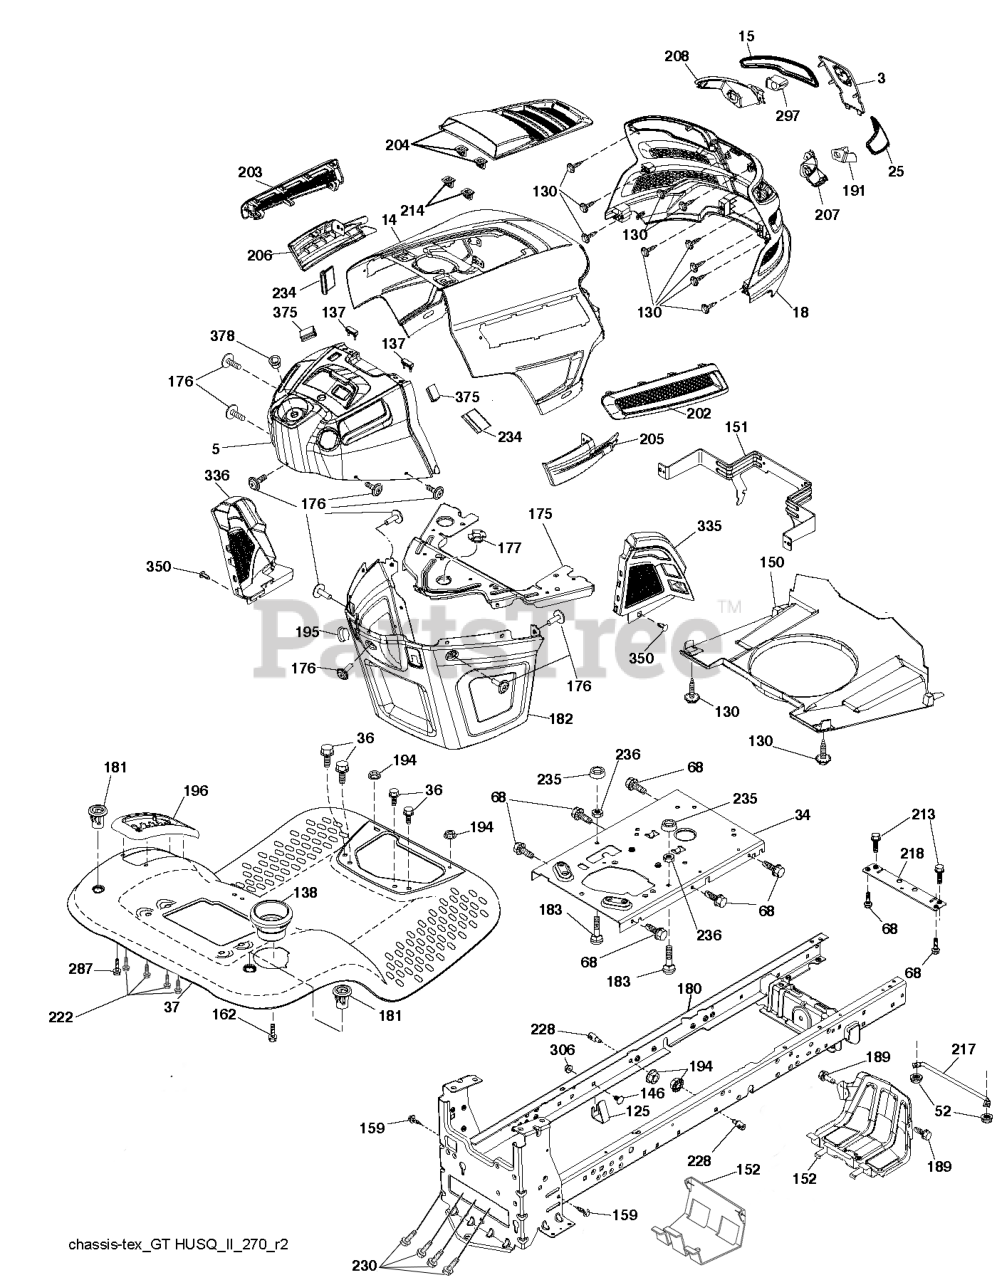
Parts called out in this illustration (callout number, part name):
3	APPLIQUE.SUBASM.GT.HUSQ.II
5	DASHBOARD.UPPER.ASM.GT2.X498
14	HOOD.ASM.HUSQVARNA.GT.TEX.ORAN
15	LENS.HEADLIGHT.LH.GTII.2011
15	LENS.LH.TEX.GT.HUSQ.CL
18	GRILLE SUBASM.GT.II.LOW.HDLGHT
25	LENS.HEADLIGHT.RH.GTII.2011
34	PLATE.ENGINE.WELDED.CHASSIS
36	SCREW 5/16"
37	FENDER.TLT.FS.W/CUPHLD.ORANGE
52	LOCKNUT
125	CLIP.FUEL.LINE
137	BUMPER DASH
138	HOLDER.CUP.LT.GREY
146	BOLT.RDHD.SHT.SQNK.3/8-16X5/8
150	AIR.DUCT.GTV.BLACK
151	BRACKET.PIVOT.HOOD.GT.HUSQ.II
152	SHIELD.BROWNING.PNT.GT.V2
152	SHIELD.BROWNING.W/TEX
159	SCREW, 3/8-16X3/4
175	PLATE.PNT.CROSSMEMBER.HUSQ/PRE
176	SCREW.#10-24X5/8.RN.QU
177	BUSHING STEERING
177	BUSHING, STEERING
180	CHASSIS
181	BUSHING.MNT.FEND.CRGO.TEX.49
182	DASH LOWER.HUSQ.PRED NO CRUISE
189	SCREW
191	INSERT.REFLECTIVE.RH.HUSQ.GTII
195	PLUG.HOLE.DASH.LOWER.12V.BLK
196	DECKLFT.CONSOL FULL ASSM GREY
202	VENT.SIDE.RH.GT.HUSQ.II.
203	VENT.SIDE.LH.GT.HUSQ.II.498
204	VENT.ASM.HOOD.TOP.TEX.
204	VENT.TOP.ASM.HUSQ.GT2
205	SIDE.TRIM.RH.GT.HUSQ.II
206	SIDE.TRIM.LH.GT.HUSQ.II.GRAY
207	HEADLIGHT.CUP.BEZEL.HUS.GT2.RH
208	BEZEL.LH.TEX.GT.HUSQ
208	HEADLIGHT.CUP.BEZEL.HUS.GT2.LH
213	SCREW HEXAGON HEAD SCREW 5/16-
214	CLIP.RETAINER.TINNER.
217	ROD.PIVOT.HOOD
218	X-PIECE.HOOD.STOP.NON/
222	SCREW.1/4-20X5/8
228	STUD.W/"D"ANTI-ROTATION
230	SHOULDER BOLT 5/16-18TT
234	BUMPER.HOOD.TEX.HUSQVARNA
235	SPACER FENDER
236	NUT.CENTERLOCK.5/16-
287	SCREW 1/4X20
297	INSERT.REFLECTIVE.LH.HUSQ.GTII
306	NUT LOCK FLG 3/8-16 UNC
335	COVER.LOWER.DASH.RH.BLACK
336	COVER-LH.LOWER.DASH.GT2.BLACK
350	CLIP.X-MAS.TREE
375	BUMPER CLIP-ON. DASH 1"
378	BUSHING FLANGE; PLASTIC
